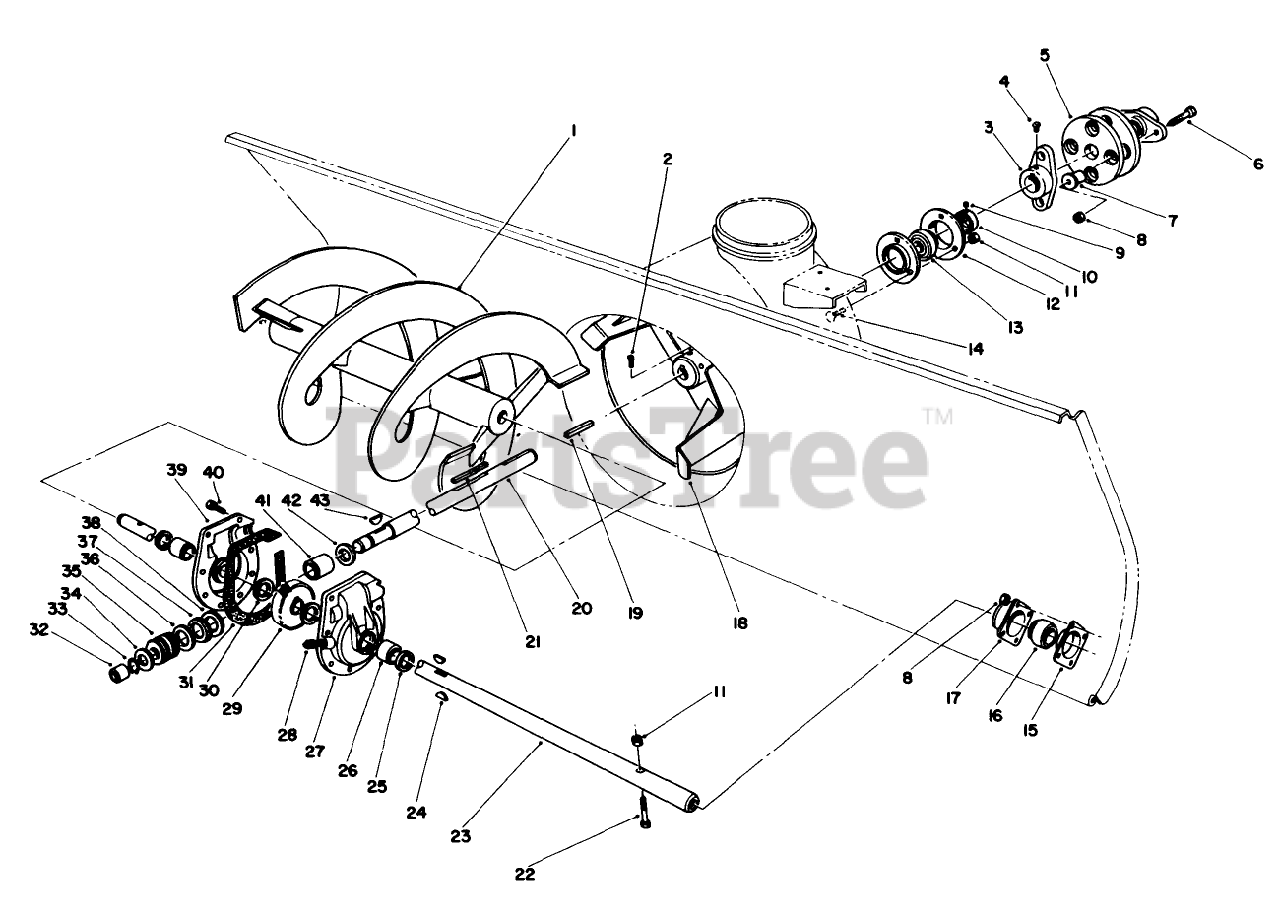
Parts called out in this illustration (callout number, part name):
1	Auger RH
2	SCREW-SET, SQH
3	HUB WA (KEY) R
4	SCREW-SET
5	COUPLING-RUBBER
6	SCREW-HH
7	SPACER-COUPLING, RUBBER
8	NUT-LOCK, NI
9	SCREW-HSH
10	EXT LOCKING COLLAR
11	NUT-LOCK, NI
12	BRG FLANGE
13	BALL BRG W/COLLAR
14	BOLT-CARR
15	BEARING-FLANGE, REAR
16	BEARING
17	BEARING-FLANGE, FRONT
18	IMPELLER ASM
19	KEY-SQUARE
20	IMPELLER SHAFT
22	SCREW-HH
23	SHAFT-AUGER
24	KEY-WOODRUFF
25	SEAL-OIL
26	BUSHING
27	Gear Case & Bushing Assy. (Incl. Ref. #25 & 26)
28	PLUG-PIPE, SQH
29	GEAR-WORM, 27T
30	WASHER-THRUST
31	GASKET-CASE, GEAR
32	BUSHING
33	Ring-Snap
34	WASHER-THRUST
36	THRUST-WASHER
37	BEARING-THRUST
38	WASHER-THRUST
39	Gear Case & Bushing Assy. (Incl. Ref. #25 & 26)
40	SCREW-TAPTITE
41	BUSHING-SPECIAL
42	RING-QUAD
43	KEY-WOODRUFF
